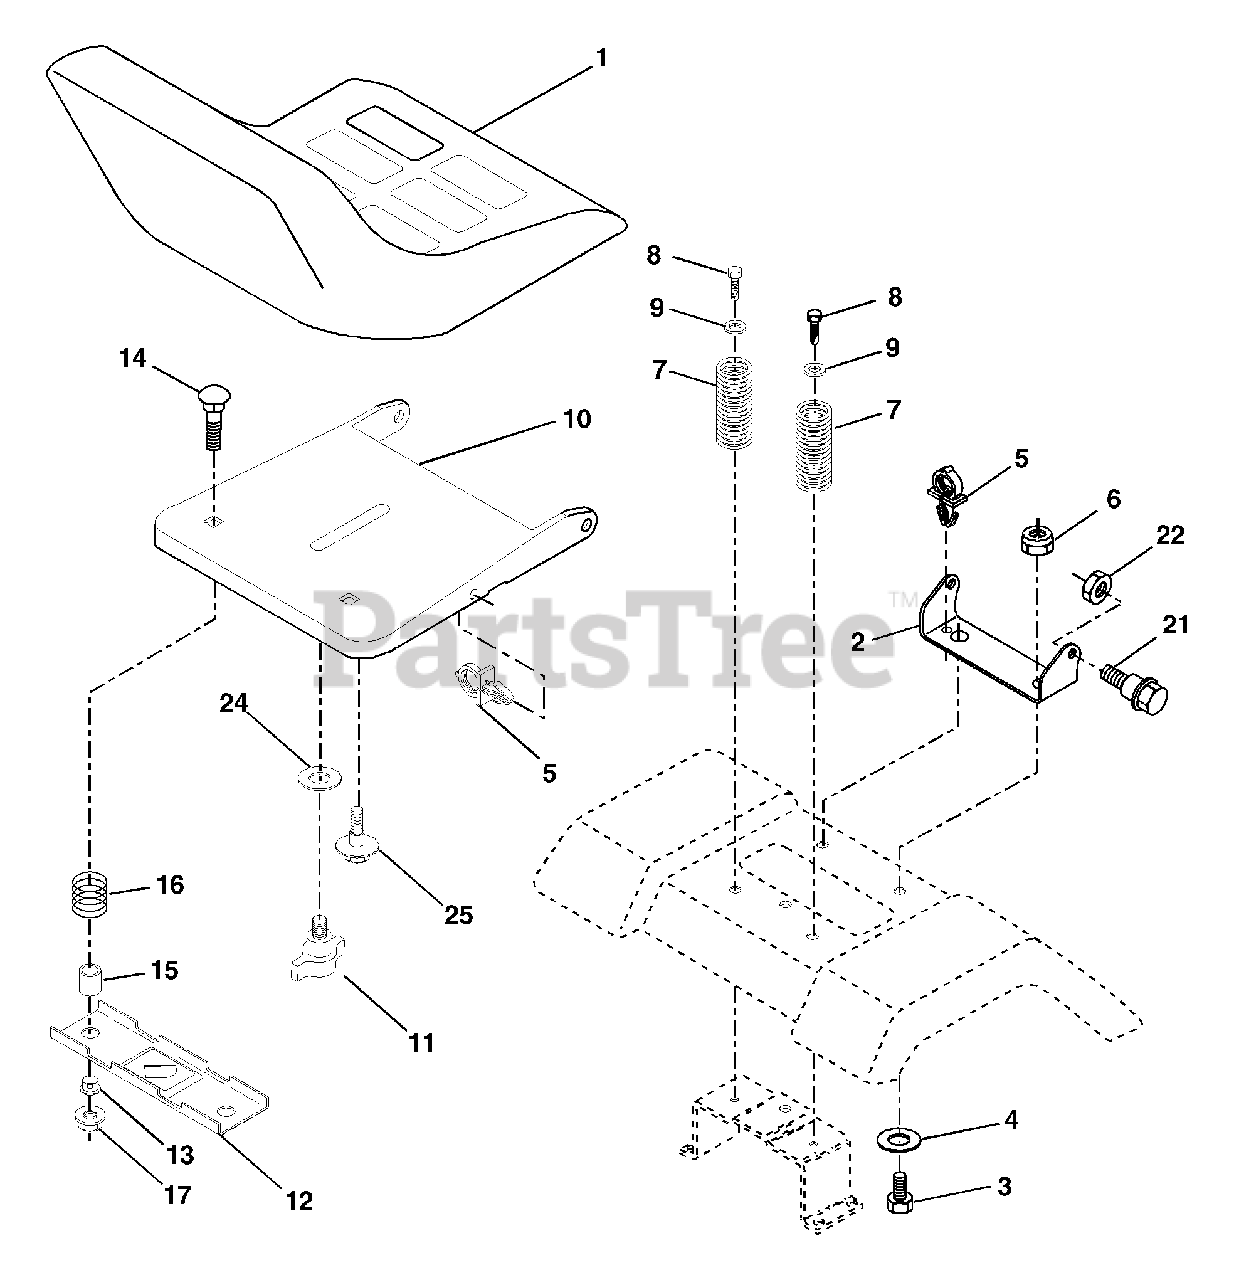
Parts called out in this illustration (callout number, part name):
1	Seat
2	Bracket Pivot Seat 8 720
3	Bolt Fin Hex 3/8-16 unc X 1
4	Washer 13/32 x 1 x 10 Ga.
5	Clip Push-In
6	Nut Hex w/Ins. 3/8-16 unc
7	Spring Seat Cprsn 2 250 Blk Zi
8	Screw 3/8-16 x 1
9	Washer 13/32 x 1 x 14 Ga.
10	Pan Seat
12	Bracket Mounting Switch
13	Bushing Snap Blk Nyl 50 Id
14	Bolt Rdhd Sqnk 1/4-20 x 1-1/2
15	Spacer Split 28x 96 Yel Zinc
16	Spring Cprsn 1 27 Blk Pnt
17	Nut Lock 1/4 Lge Flg Gr. 5 Zinc
21	Bolt Shoulder 5/16-18 unc-2A
22	Nut Hex Lock W/Ins 5/16-18
24	Washer 17/32 x 1-3/16 x 12 Ga.
25	Bolt Shoulder 5/16-18 x .62
